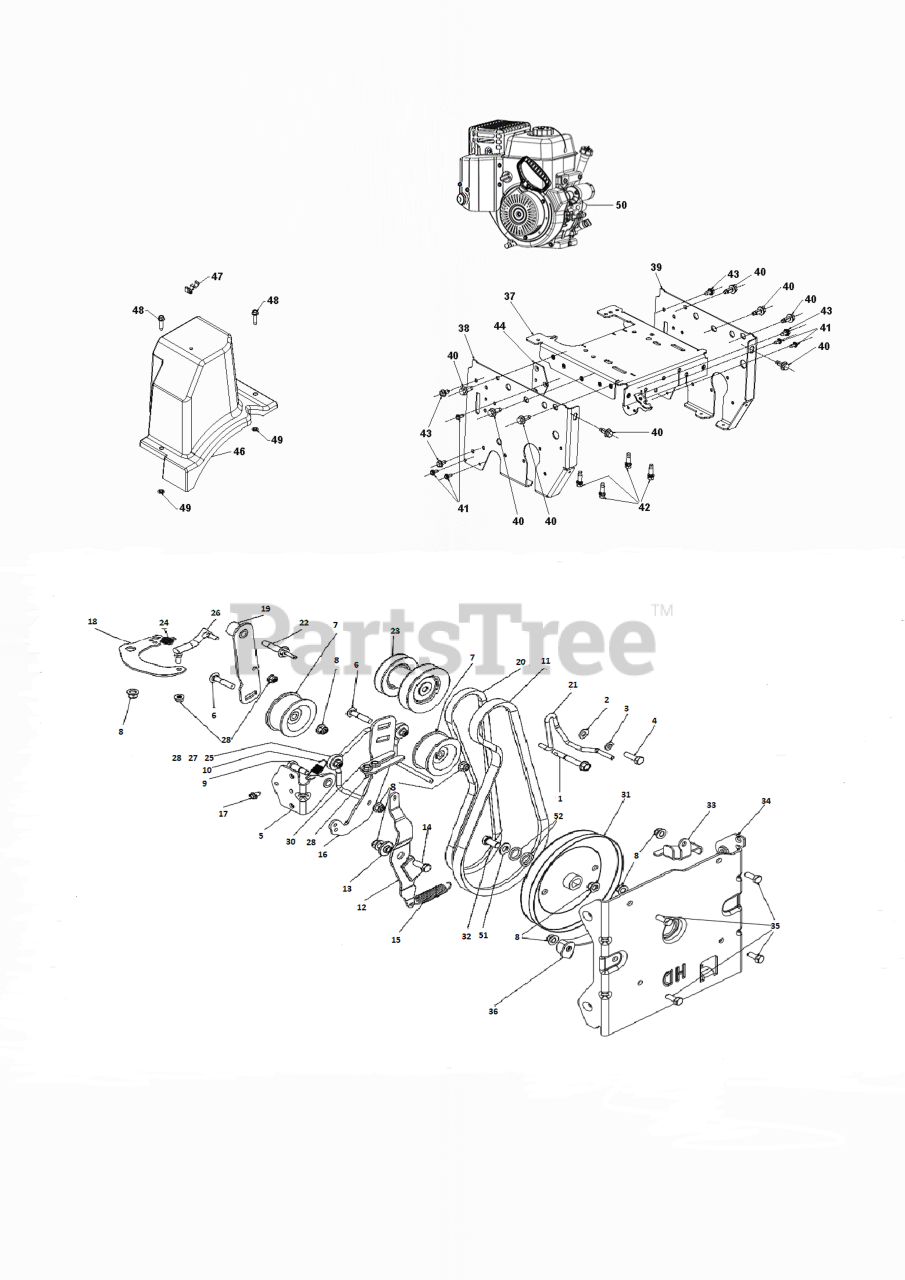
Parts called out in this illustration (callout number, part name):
1	BOLTS
2	WASHER 11/32 X 11/16 X 14 GA T
3	WASHER SPRING LOCK WASHER WITH
4	SCREW
5	BRACKET WELDMENT, IDLER ARM ZI
6	BOLT 5/16-18 CARRIAGE 1.5L
8	NUT HEXAGON FLANGE 5/16-18 ST
9	SCREW HEX HEAD SHOULDER
10	SCREW HEX HEAD SHOULDER
11	BELT 5L 39.15L
12	ARM IMPELLER BRAKE
13	BUSHING.BRAKE.ARM
14	BOLT HEXAGON BOLT 5/16-18 X 7/
15	SPRING EXTENSION - BRAKE
16	ARM IDLER BLACK ZINC
17	SCREW
18	Bell Cranks
19	ARM DRIVE IDLER BLACK ZINC PLA
20	BELT 4L DRIVE
21	Belt Keepers
22	GUIDE BELT, SHOULDER SCREW
23	PULLEY 5L HYDRO
24	SPRING EXTENSION - DRIVE
25	GUIDE BELT - HYDRO 2 WITH FAN
26	LINK ASSY DRIVE IDLER
28	NUT FLG, NYLOCK, 1/4-20 GR G C
30	HEX.WASHER.HEAD 1/4-20 X .65
31	PULLEY IMPELLER DD 5L HD
32	SCREW HEXAGON HEAD FLANGE 3/8-
34	BRACKET AUGER HOUSING INTERFAC
35	SCREW HEXAGON HEAD SCREW 5/16-
36	BRACKET.BELT.KEEPER.LOWER.BLAC
40	SCREW HEXAGON HEAD FLANGE 3/8-
41	SCREW 14-20 X 5/8
42	BOLT 3/8-16X1-1/8
43	BOLT.HEX.HD.WASHER.5/16-18X.75
44	BRACKET NUT BLACK ZINC PLATE
46	COVER BELT ASM HIGH CRANK
48	SCREW HEX WASH THDRL BLK 1_4-
49	PALNUT 1/4
50	ENGINE RATO 389CC (EFI)
50	ENGINE LCT 369CC 11HP E-GOV
51	WASHER PLAIN WASHER 3/8 X 0.08
52	WASHER.SPACER.MANDREL
